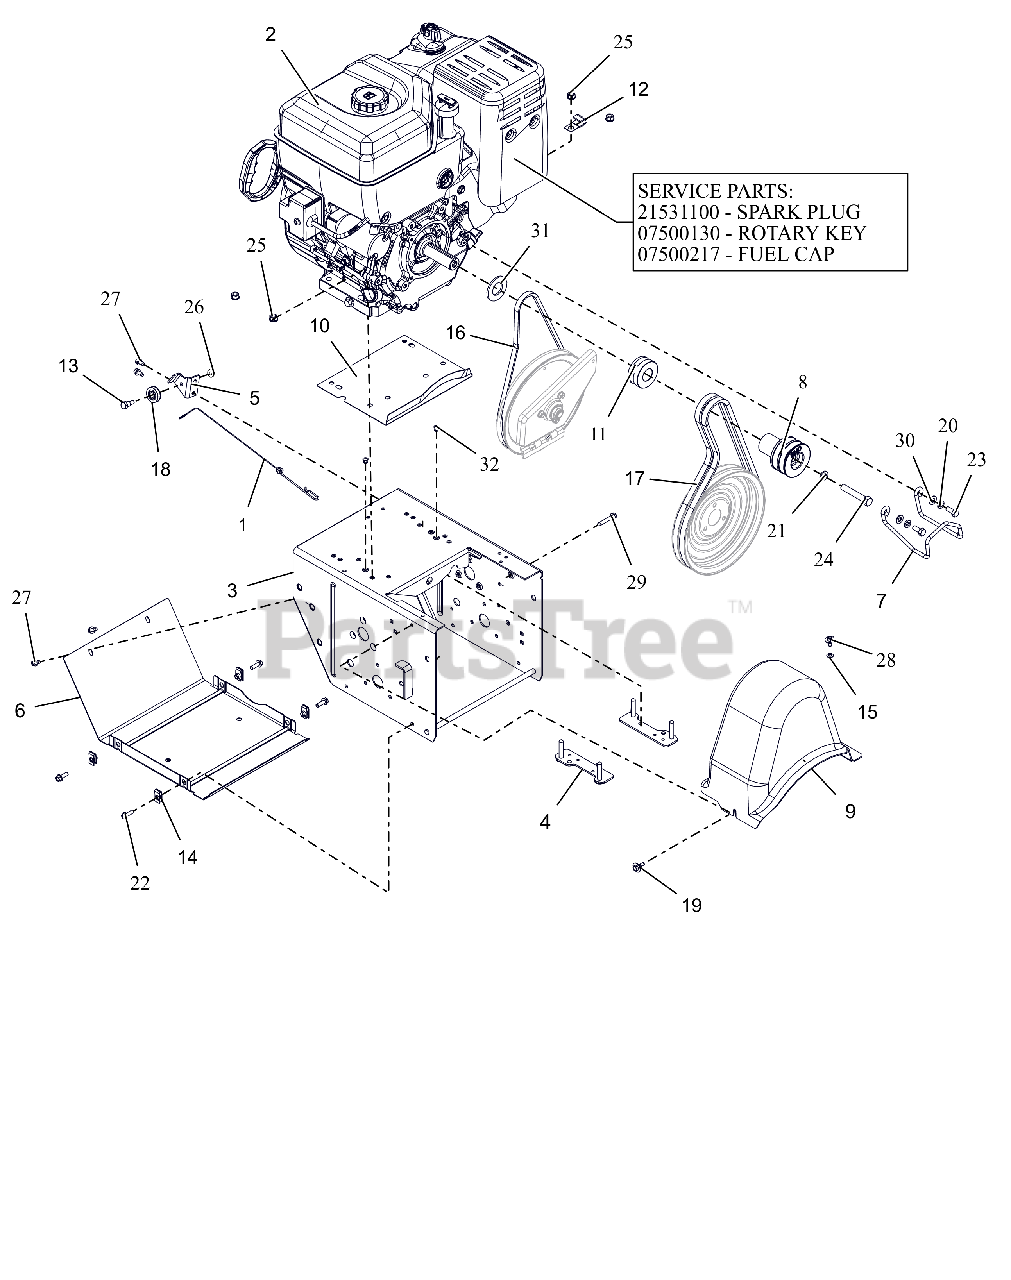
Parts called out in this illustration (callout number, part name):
1	CABLE, LOWER TRACTION,SS & PRO
2	ENGINE, BRIGGS PF 2100, 240V
2	PLUG, SPARK 20HP B&S VANGUARD
2	KEY, IGNITION ROTARY B&S
2	CAP, FUEL - BRIGGS & STRATTON
3	FRAME, MAIN - PRO (WELDMENT)
4	STRAP, BOLT-LARGE
5	BRACKET, CABLE PULLEY
6	COVER, BOTTOM
7	FINGER, BELT
8	SHEAVE,ATTACHMENT-SHO 2 GRV
9	COVER, BELT-LARGE
10	BAFFLE, WATER - LARGE BLOCK
11	SHEAVE, TRACTION DRIVE
12	J-CLAMP
13	BOLT, SHLDR -.375 X .375 X .25-20
14	NUT-RTNR .25-20X.56
15	NUT-PUSH .25X.50 O.D.
16	V-BELT, 3L-WRAPPED
17	V-BELT, HA-RAW EDGE (SET)
18	PULLEY, CABLE
19	SCR-TAP .25-20X.5 CAPTIVE
20	WSHR, LK-HVY .312X.097 ZCC
21	WSHR, LK-REG .438X.109 ZCC
22	BLT, HWH .25-20X.75 G5 ZCC
23	BLT, HEX .31-24X.750 G5 ZCC
24	BLT, HEX .44-20X2.50 G5 ZCC
25	NUT,LK-CTR-FLG .31-18 GF ZCC
26	NUT-LK-TOP-FLG .250-20 GF ZCC
27	SCR-TAP .25-20X.50 HWH ZCC
28	SCR, TAP .25-20X.50 LG HWH ZCC
29	SCR,TAP .25-20X1.50 HWH TR ZCC
30	WSHR,FLT .344X.688X.065 ZCC
31	WSHR, FLT 1.062X2.000X.134 ZCC
32	RVT, POP .1875 ZCC
